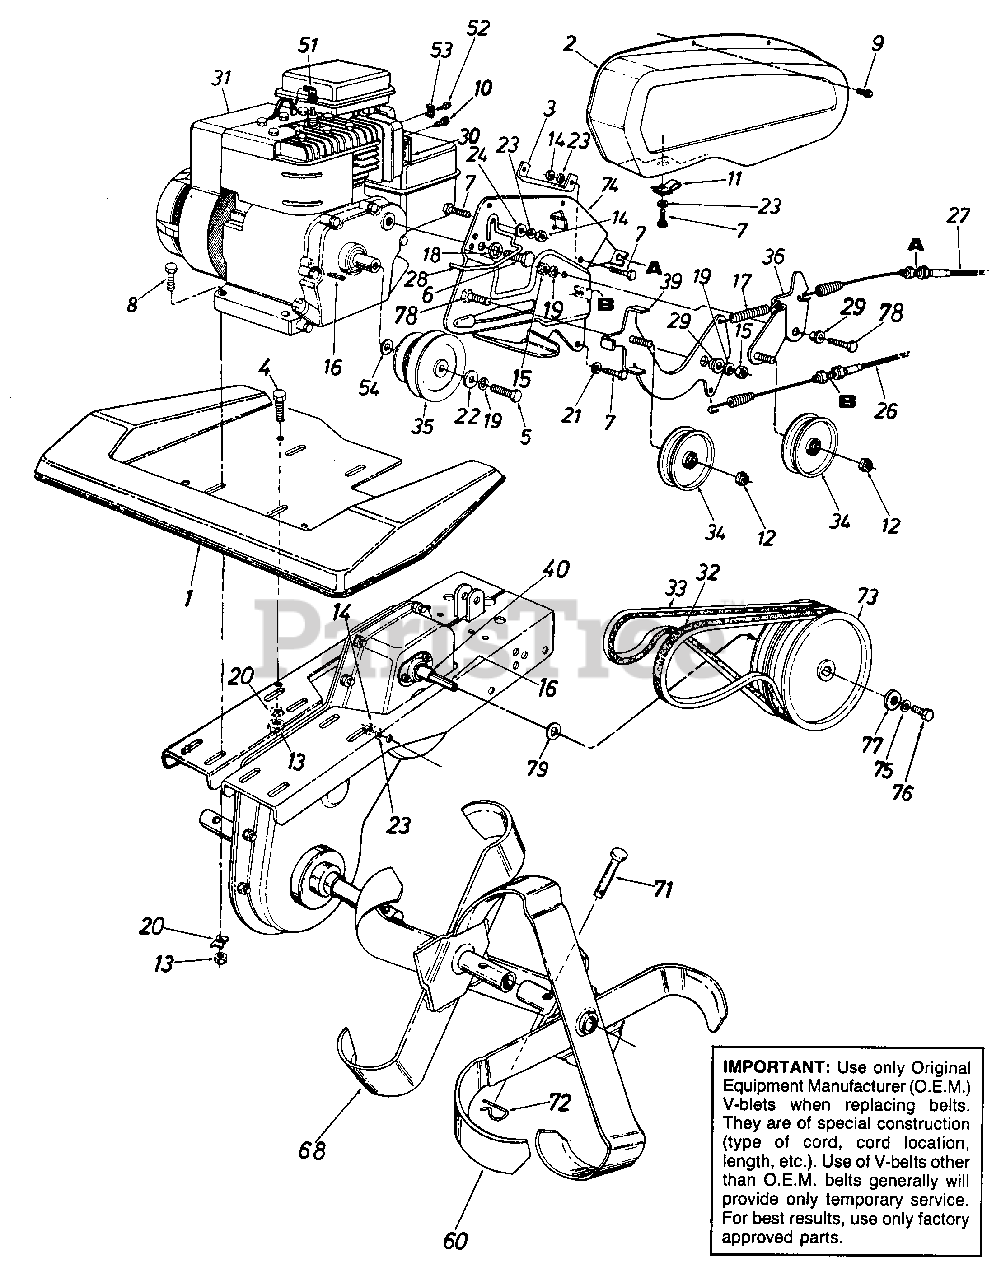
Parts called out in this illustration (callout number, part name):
4	SCREW-HEX 5/16-18 X .75
5	SCREW 3/8-24 X 1.25 GR5
6	SCREW-HEX 5/16-24 X .62
7	SCREW-HEX 1/4-20 X .75
8	SCREW-HEX 5/16-18 X 1.50
9	SCREW-HEX WASH SF TAPP
10	SCREW-HEX WASH HD 10-32X.38
11	NUT-SPEED-1/4-20
12	NUT-HEX CENTER JAM 3/8-24
13	NUT-HEX 5/16-18
14	NUT-HEX 1/4-20
15	NUT-HEX CENTER L-3/8-16
16	KEY-SQ 3/16X1.50
17	SPRING-EXTENSION
18	WASHER-LOCK-5/16
19	WASHER-LOCK-3/8
20	WASHER-SPEC L 5/16 X .88 OD
21	WASHER-SPRING.270 ID X.51 OD X.030
22	WASHER-FL-.385 X 1.00 X .135
23	LOCK WASHER 1/4 DIA
24	WASHER-FL
26	CABLE-CLUTCH CONTROL
27	CABLE-CLUTCH CONTROL
28	ROD-BELT GUARD
29	SPACER-SHLD
30	DEFLECTOR-MUFFLER
31	ENGINE
32	BELT-V 1/2 X 37 SPECIAL
33	BELT-V 1/2 X 41
34	PULLEY-IDLER-FLAT W/FLANGES
35	PULLEY-ENGINE
40	SPACER-.635 ID X .88 OD X 1.03
51	INSULATOR-SPARK PLUG
52	SCREW-HEX SEMS #10-32
53	CLAMP-CASING
54	WASHER-FL
68	TINE ASSY-INNER-LH
71	PIN-CLEVIS
72	PIN-COTTER
74	PLATE-CLUTCH MTG
75	WASHER-LOCK-5/16
76	SCREW-HEX 5/16-18 X 10 SPEC
77	WASHER-FL-.312 X 1.125 X .125
78	BOLT-3/8 NF X 1"GR5
79	WASHER-FL-.640ID X 1.24OD X .06HDN
